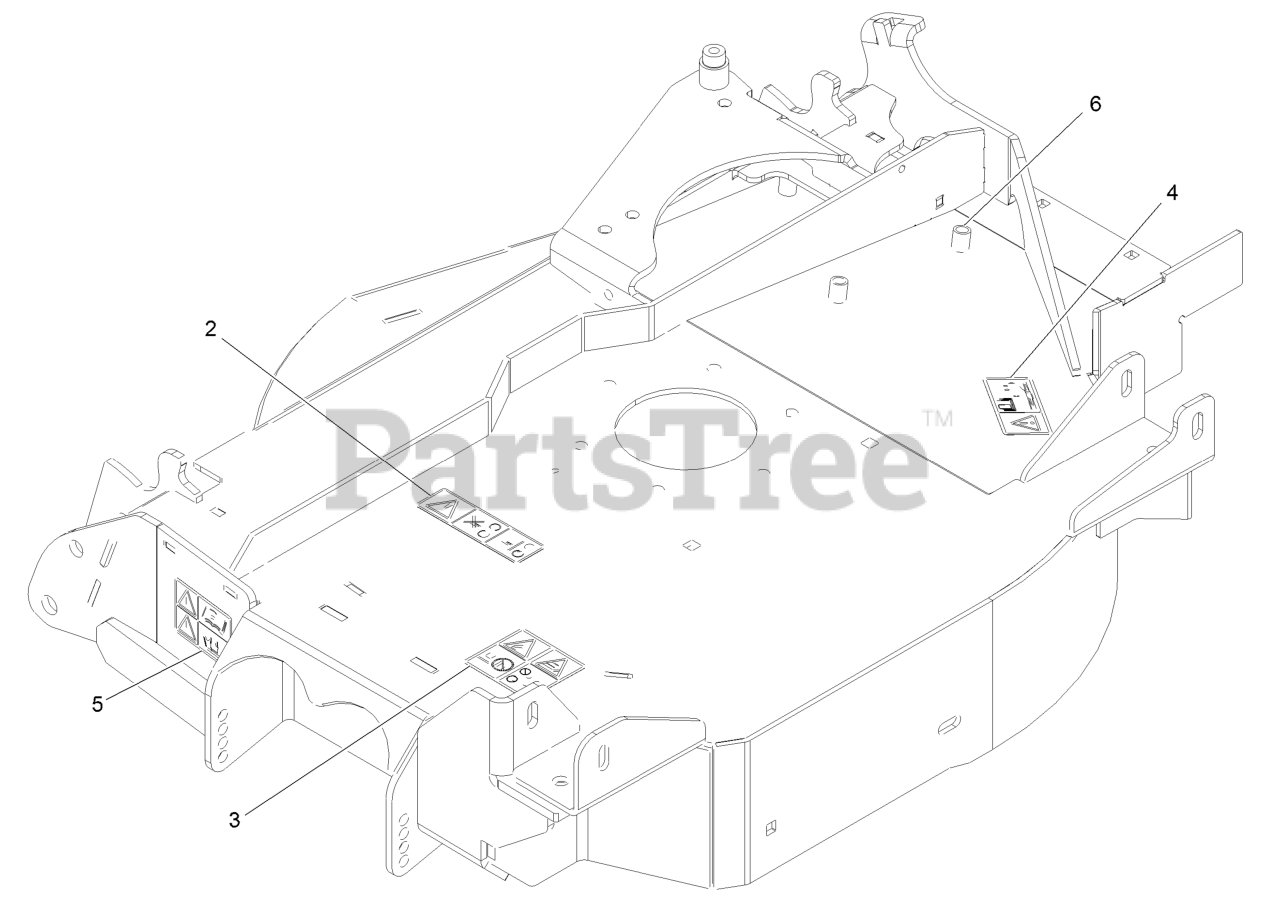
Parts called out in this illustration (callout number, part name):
2	Decal-Cover, Missing
3	Decal-Danger, Thrown Object
4	Decal-Bolt Torque
5	Decal-Warning, Pinch Point
6	Insert-Nut
